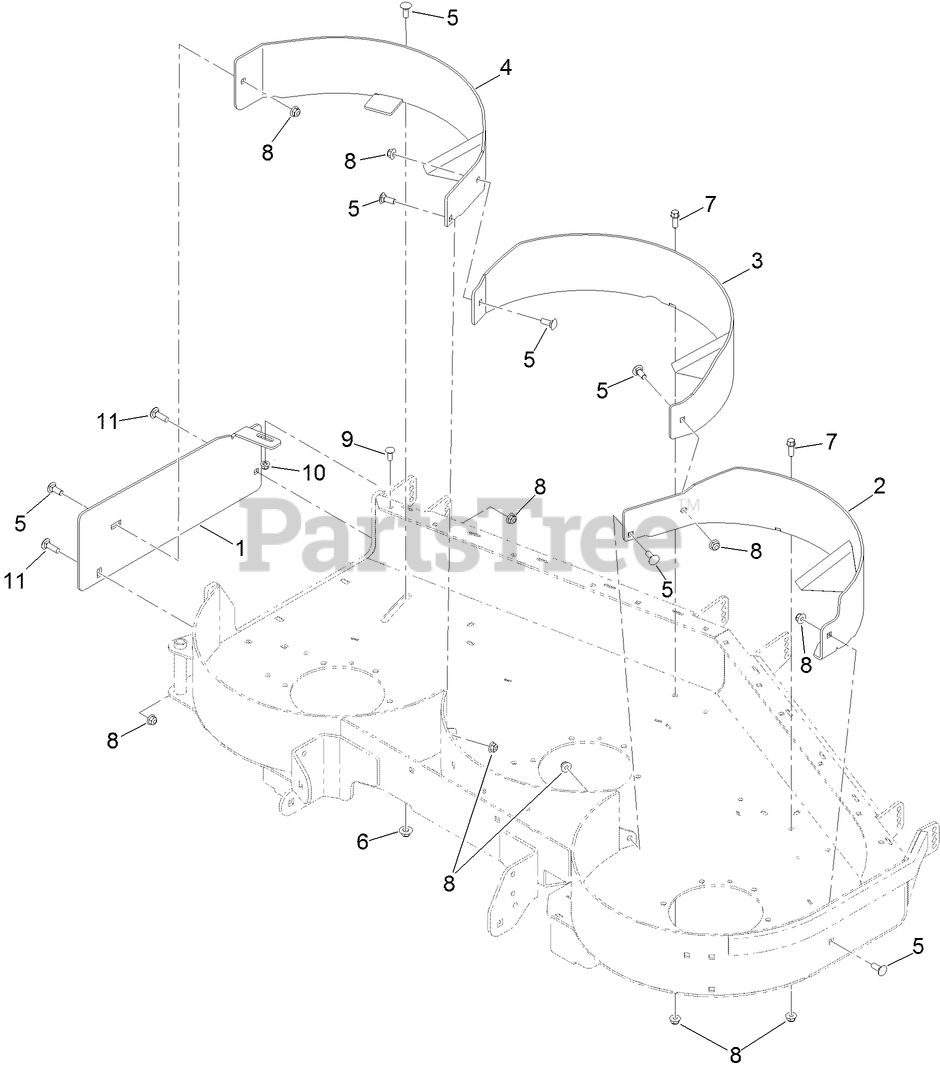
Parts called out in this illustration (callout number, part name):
1	PLATE-COVER, DISCHARGE
2	BAFFLE-RECYCLER, LH
3	BAFFLE-CENTER
4	BAFFLE-RH
5	BOLT-CARR
6	NUT-FLANGE, NI
8	NUT-HF, NI
9	SCREW-CARR
10	NUT-HF, NI
11	BOLT-CARR
